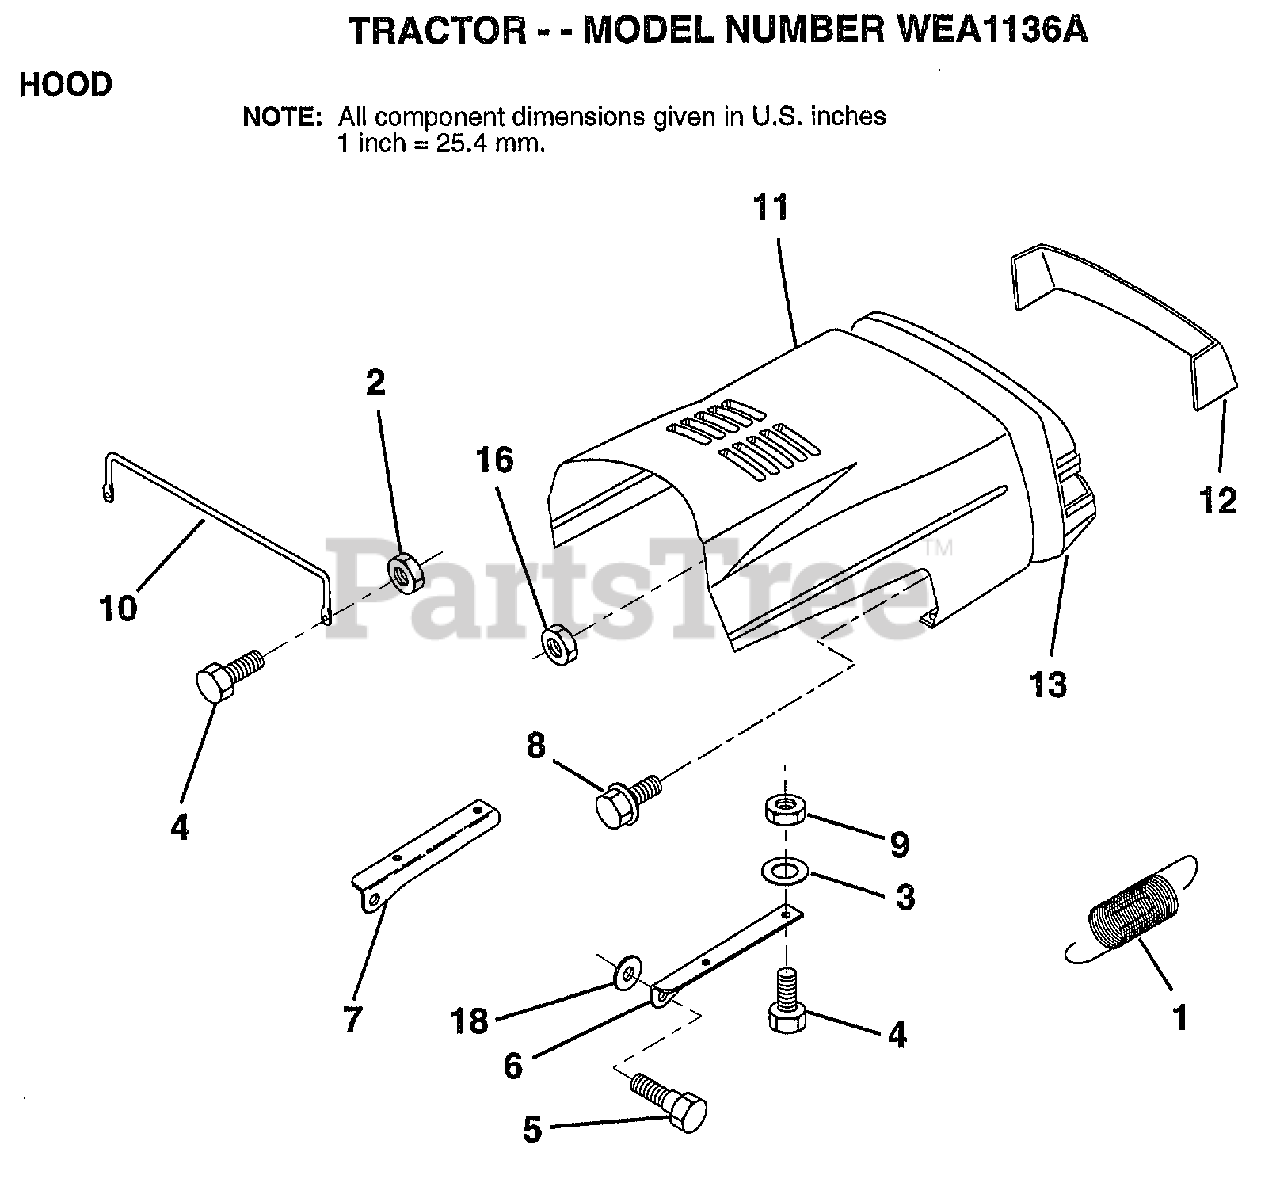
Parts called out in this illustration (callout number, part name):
1	EXT SPRING
2	NUT
3	WASHER
5	BOLT.SHLD.5/16-18
6	BRKT HOOD RH
7	BRKT HOOD LH
8	SCREW SLTD HXHD
9	NUT
10	"BRACE,HOOD"
11	HOOD.IMPREG.MS550
12	LENS.BAR.CLEAR.LR
13	GRILL
16	NUT
18	WASHER
